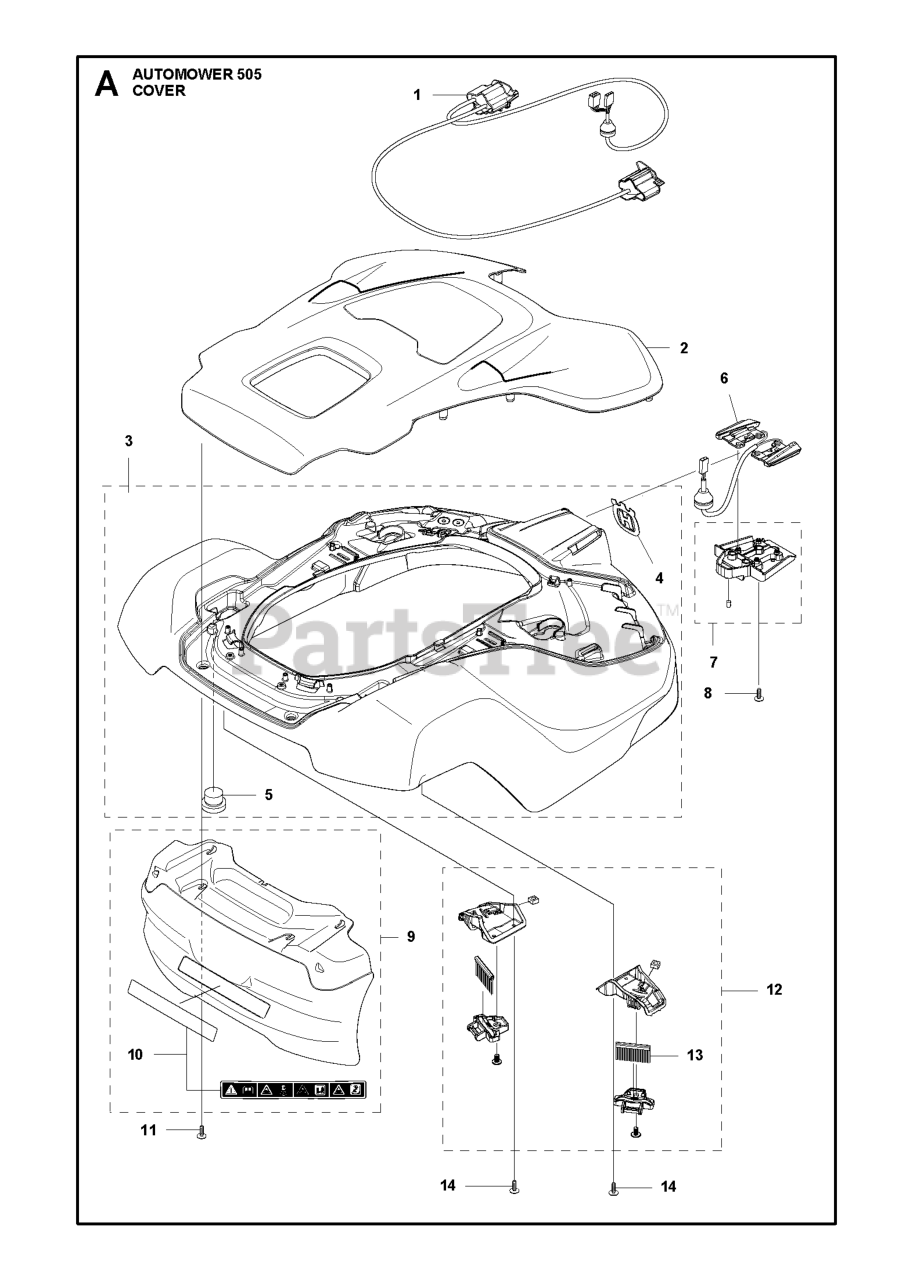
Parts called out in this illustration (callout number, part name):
1	WIRING ASSY ULTRA SONIC SENSOR
3	BODY ASSY
4	DECAL HUSQVARNA CROWN HEIGHT 5
5	CAP SNAPLOC
6	CABLE ASSY CHARGING PLATE
7	HOLDER ASSY MAGNET
8	SCREW 14MM
9	BUMPER ASSY
10	LABEL WARNING P15
11	SCREW ITXPANT
12	BRUSH KIT 430/450
13	WHEEL BRUSH REFILL KIT
14	SCREW 14MM
